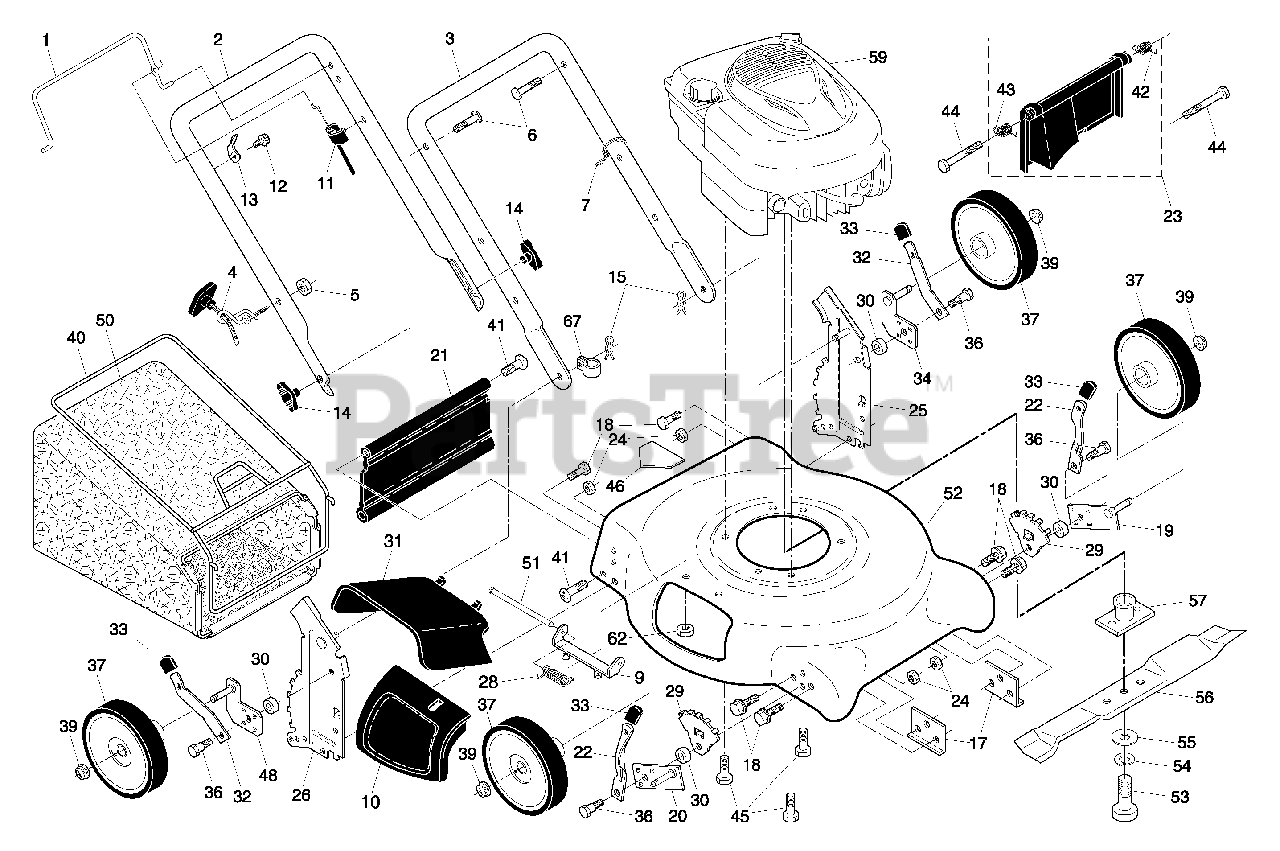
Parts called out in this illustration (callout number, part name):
1	Control Bar
2	Upper Handle
3	Lower Handle
4	Rope Guide
6	Handle Bolt
7	Wire Tie
9	Hinge Bracket
10	Mulcher Door
11	Cable, Engine Zone Control
12	Hex Washer Head Screw
13	Up-Stop Bracket
14	Knob, Handle
15	Hairpin Cotter
17	Support Bracket
18	Screw
19	Axle Arm Assembly, Front, LH
20	Axle Arm Assembly, Front, RH
21	Rear Skirt
22	Selector Spring, Front
23	Kit, Rear Door Assembly
24	Locknut, Hex 5/16-18
25	Handle Bracket Assembly, LH
26	Handle Bracket Assembly, RH
28	Spring, Hinge
29	Wheel Adjusting Bracket, Front
30	Spacer
31	Discharge Deflector
32	Selector Spring, Rear
33	Selector Knob
34	Axle Arm Assembly, Rear, LH
36	Shoulder Bolt 5/16-18
37	Wheel & Tire Assembly
39	Flanged Locknut, Hex
40	Frame, Grassbag
41	Hinge Screw
42	Spring, Rear Door, LH
43	Spring, Rear Door, RH
44	Bolt, Rear Door
45	Hex Head Thread Rolling Screw 3/8-16 x 1
46	Danger Decal
48	Axle Arm Assembly, Rear, RH
50	Grassbag
51	Rod, Hinge
52	Kit, Lawn Mower Housing
53	Hex Head Screw 3/8-24 x 1-3/8 Grade 8
54	Helical Lockwasher
55	Hardened Washer
56	21" Blade
57	Blade Adapter
62	Nut, Hex
67	Clip, Cable
